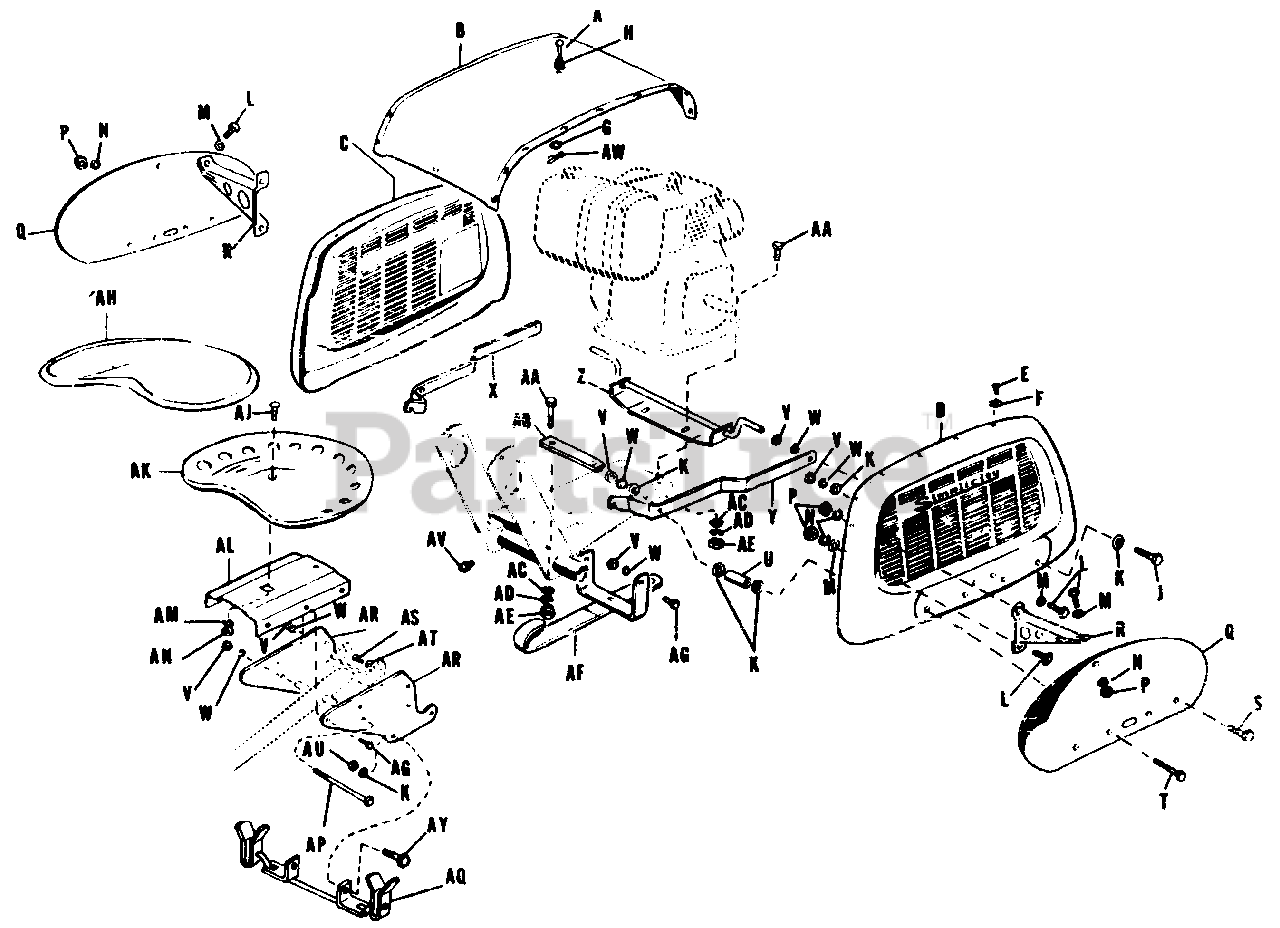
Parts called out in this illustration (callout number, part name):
A	Rivet, Engine Shut-off
B	Panel, Top
C	Panel, Side, R.H.
D	Panel, Side, L.H.
E	Screw, 10 x 1/2
F	Speed Nut
G	Washer, Plain, 3/16
J	Capscrew, Hex Hd., 3/8-16 x 1 1/4
K	Washer, Lock
L	Capscrew, Hex Hd., 1/4-20 x 1/2
M	Washer, Plain, 1/4
N	Lockwasher, 1/4
P	Nut, Full Hex, 1/4-20.
R	Brace, Fender
S	Capscrew, Hex Hd., 3/8-16 x 5/8
T	Capscrew, Hex Hd., 3/8-16 x 2
U	Spacer, Latch
V	Nut, Full Hex, 3/8-16
W	Washer Lock, 3/8
X	Latch Arm, R.H.
Y	Latch Arm, L.H.
Z	Bracket Assembly, Pivot
AA	Capscrew, Hex Hd., 5/16-18 x 1 3/4
AB	Spacer, Engine
AC	Washer, Plain, 5/16
AD	Washer, Lock, 5/16
AE	Nut, Full Hex, 5/16-18
AF	Draw Bar Assembly
AG	Capscrew, Hex Hd., 3/8-16 x 1
AH	Pad, Seat
AJ	Carriage Bolt, 1/2-13 x 1
AL	Support, Seat
AM	Washer, Lock, 1/2
AN	Nut, Full Hex, 1/2-13
AP	Bolt, Sq. Hd. Machine, 3/8-16 x 6
AQ	Catch Assembly
AR	Side Plate
AS	Capscrew, Hex Hd., 7/16-20 x 3/4
AT	Washer, Lock, 7/16 Internal Shakeproof
AU	Nut, Full Hex,
AV	Grease Fitting, Alemite #1637
AW	Pin, Cotter, 3/32 x 1 long
AX	Clip, for trim
AY	Capscrew, 3/8-16 x 7/8
